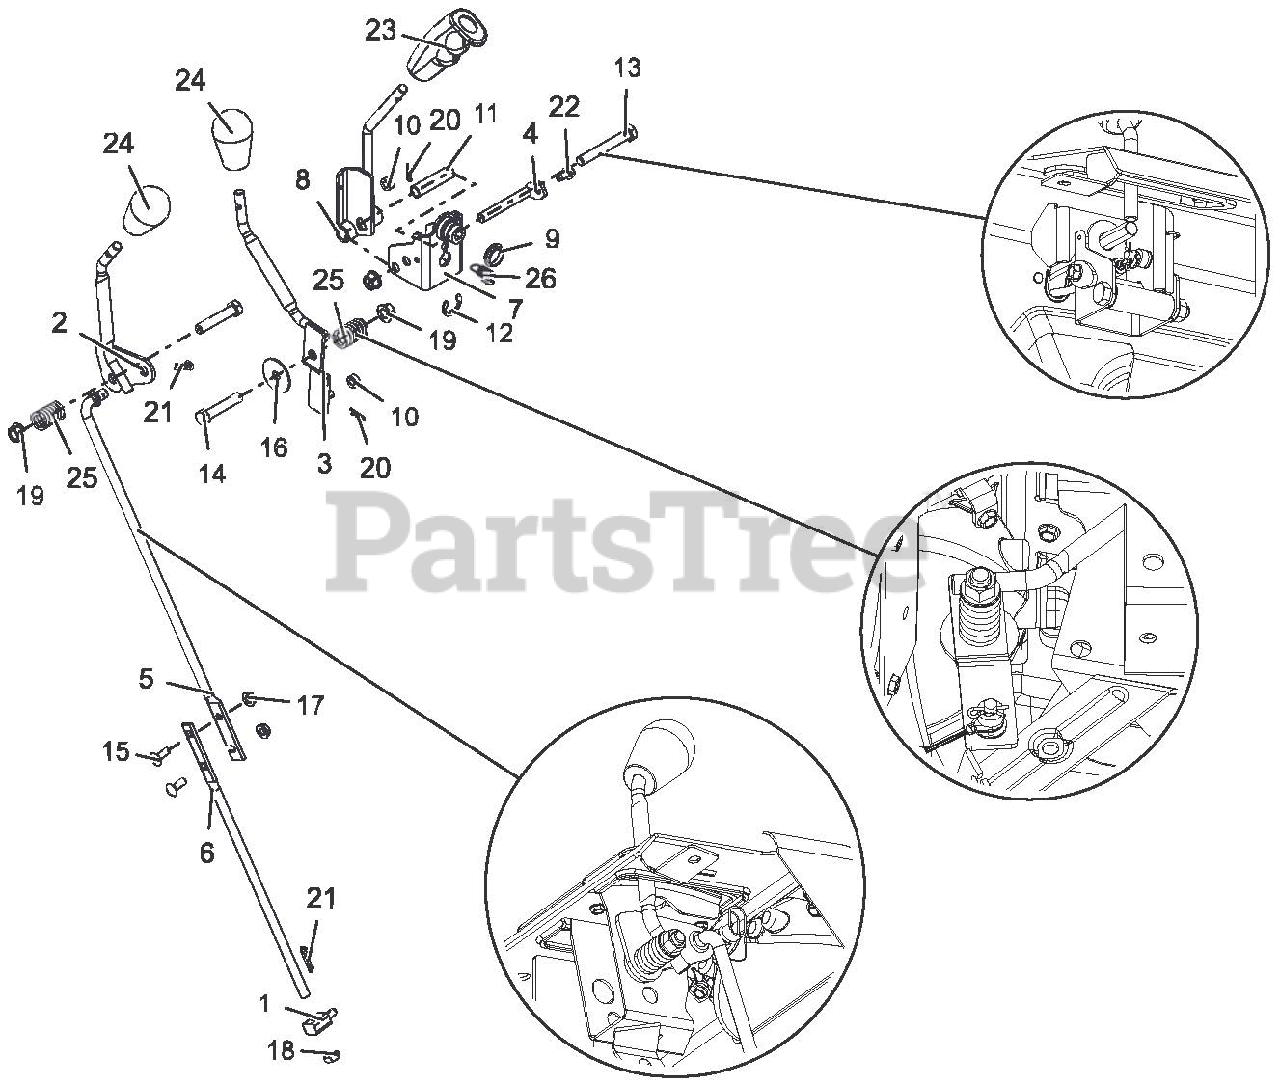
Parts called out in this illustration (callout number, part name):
1	PIVOT,SHIFT ROD .375-16(TRUNN)
2	WELDMENT, CONTROL LEVER(SHIFT)
3	WELDMENT, CONTROL LEVER (DEFL)
4	ROD, PIVOT - INTERLOCK
5	ROD, SHIFT - UPPER
6	ROD. HYDRO SHIFT - LOWER
7	WELDMENT-CONTROL BRACKET-CHUTE
8	WELDMENT, CONTROL LEVER
9	BUSHING, POLYLINER-.75 SNAPIN
10	BSHG-SLV .265X.500X.219
11	SPCR, WHEEL .385X.500X2.00
12	E-RING .750X.050
13	@BLT-HEX .38-16X2.75 GR5 YWZC
14	@BLT-HEX .38-16X2.00 GR5 YWZC
15	@BLT-RDHDSQNK .25-20X.75 G5YZ
16	WSHR-FL-STL .380X1.50X.062 YWZ
17	@NUT-LK-CTR-FLG .25-20 YWZC
18	NUT-HEX-JAM .375-16 YWZC
19	@NUT-LK-TOP-FLG .38-16 YWZC
20	PIN-HAIR INT .06X.18X.77
21	PIN-HAIR INT .08X.18X1.18 YWZC
22	SCR-TAP .25-20X.50 HWH TR YWZ
23	CONTROL HANDLE, QUICK TURN
24	KNOB,SOFT TEARDROP,PUSH-ON GRY
25	SG-COMP .125X.781X1.250
26	SPRING-EXT .047X.438X1.45
